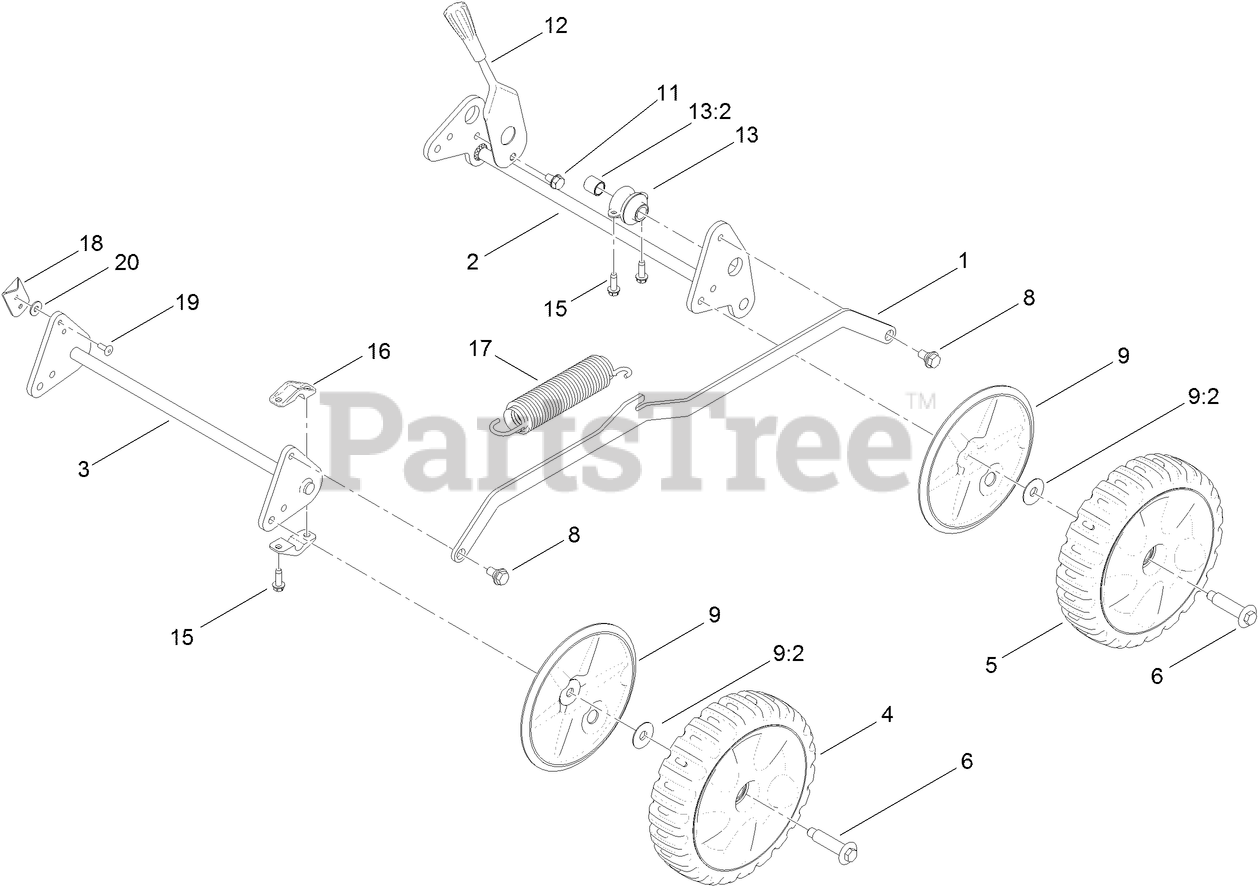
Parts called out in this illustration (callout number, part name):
1	BAR-CROSS, HOC
2	BAR-PIVOT, REAR
3	BAR-PIVOT, FRONT
4	8 INCH WHEEL ASM
5	8 INCH WHEEL AND GEAR ASM
6	BOLT-SHOULDER
8	SCREW-SHOULDER
9	WHEEL COVER ASM
9:2	WASHER-STEPPED
11	SCREW-HHF
12	HANDLE-LIFT ASSIST
13	BUSHING ASM
13:2	BUSHING
15	SCREW-HWHTF
16	MOUNT-AXLE, FRONT
17	SPRING-EXTENSION
18	INDICATOR-HOC
19	RIVET-BLIND
20	WASHER-FLAT
